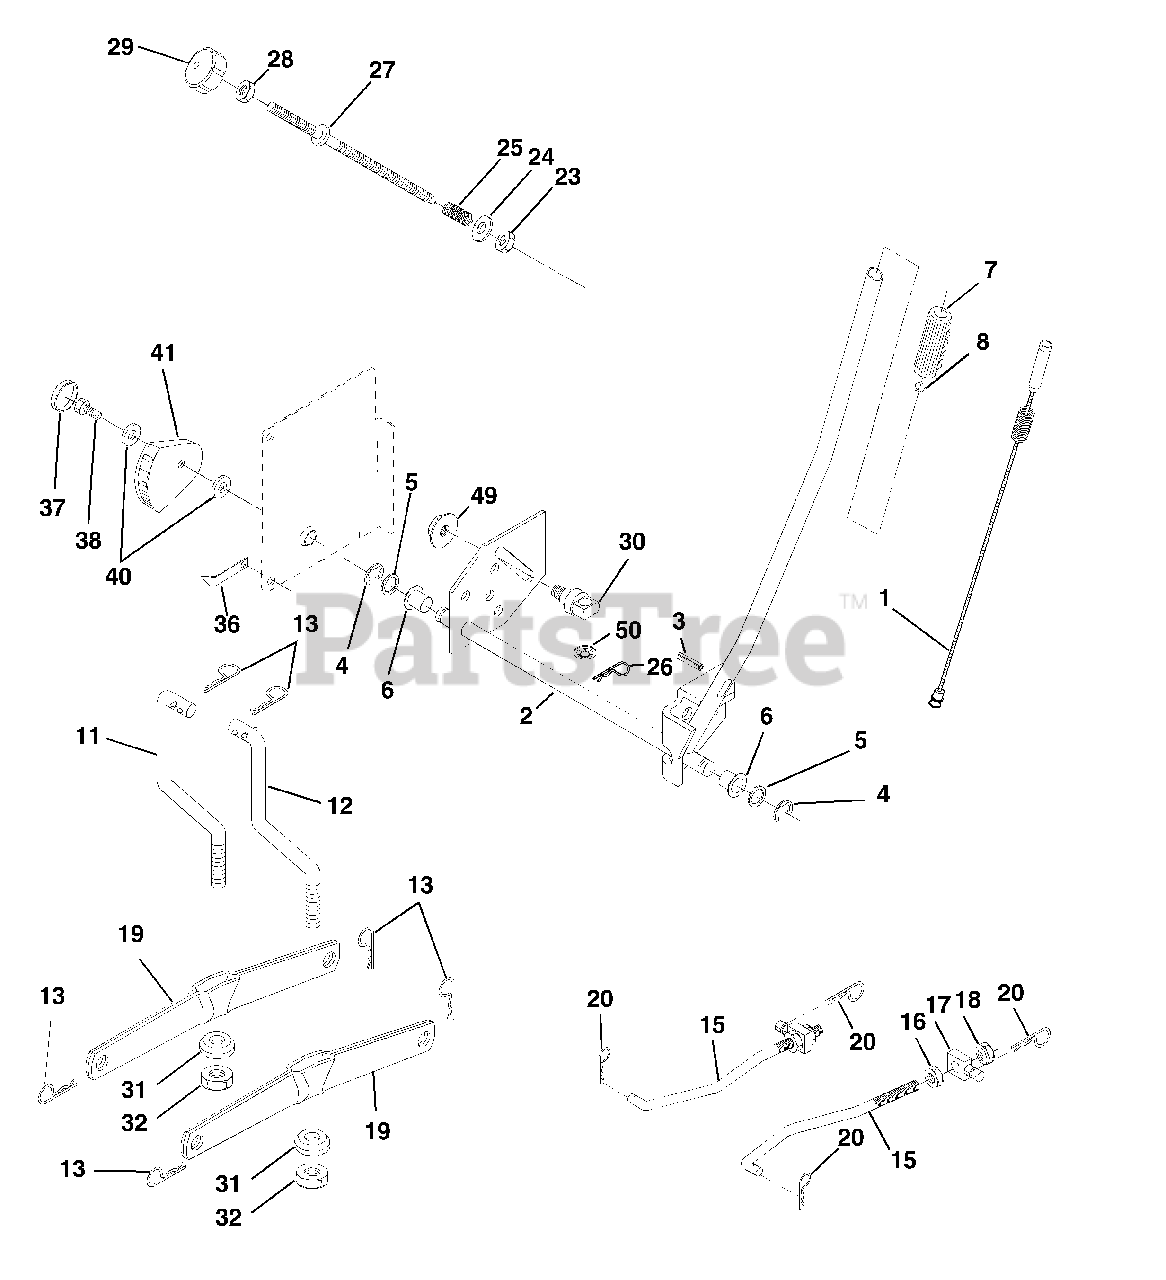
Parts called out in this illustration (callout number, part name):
1	Wire Asm Inner/Sprg W/plunger LT
2	Shaft Asm Lift RH w/Inf
3	Pin Groove 1 500 Zinc
4	E Ring #5133-62
5	Washer 21/32 X 1 X 21 Ga
6	Bearing Nylon Blk 629 Id
7	Grip Handle
8	Button Plunger
11	Link Lift LH Fixed Length
12	Link Lift RH Fixed Length
13	Retainer Spring
15	Link Front
16	Nut Jam Hex 1/2-13 Unc
17	Trunnion
18	Nut Lock W/Wsh 1/2-13 Unc
19	Arm Suspension Rear
20	Retainer Spring
23	Nut Special
24	Washer 13/32 X 5/8 X 16 Ga
25	Spring 2-1/8"
26	Retainer Clip
27	Rod Adj Lift Zinc 7.49 Wrk Lg
28	Nut Hex Jam 3/8-16 Unc
29	Knob Inf 3/8-16 Unc Blk W/sym
30	Trunnion Infin Height
31	Bearing Pvt Lift
32	Nut Crownlock 3/8 - 24
36	Pointer Height Indicator
37	Plug Hole Blk 1.485/1.515 Dia.
38	Screw 5/16-18 x 1
40	Washer 11/32 x 1-1/2 10 Ga.
41	Indicator Height STLT
49	Nut Hex Flange Lock
50	Nut PUsh Phos & Oi
